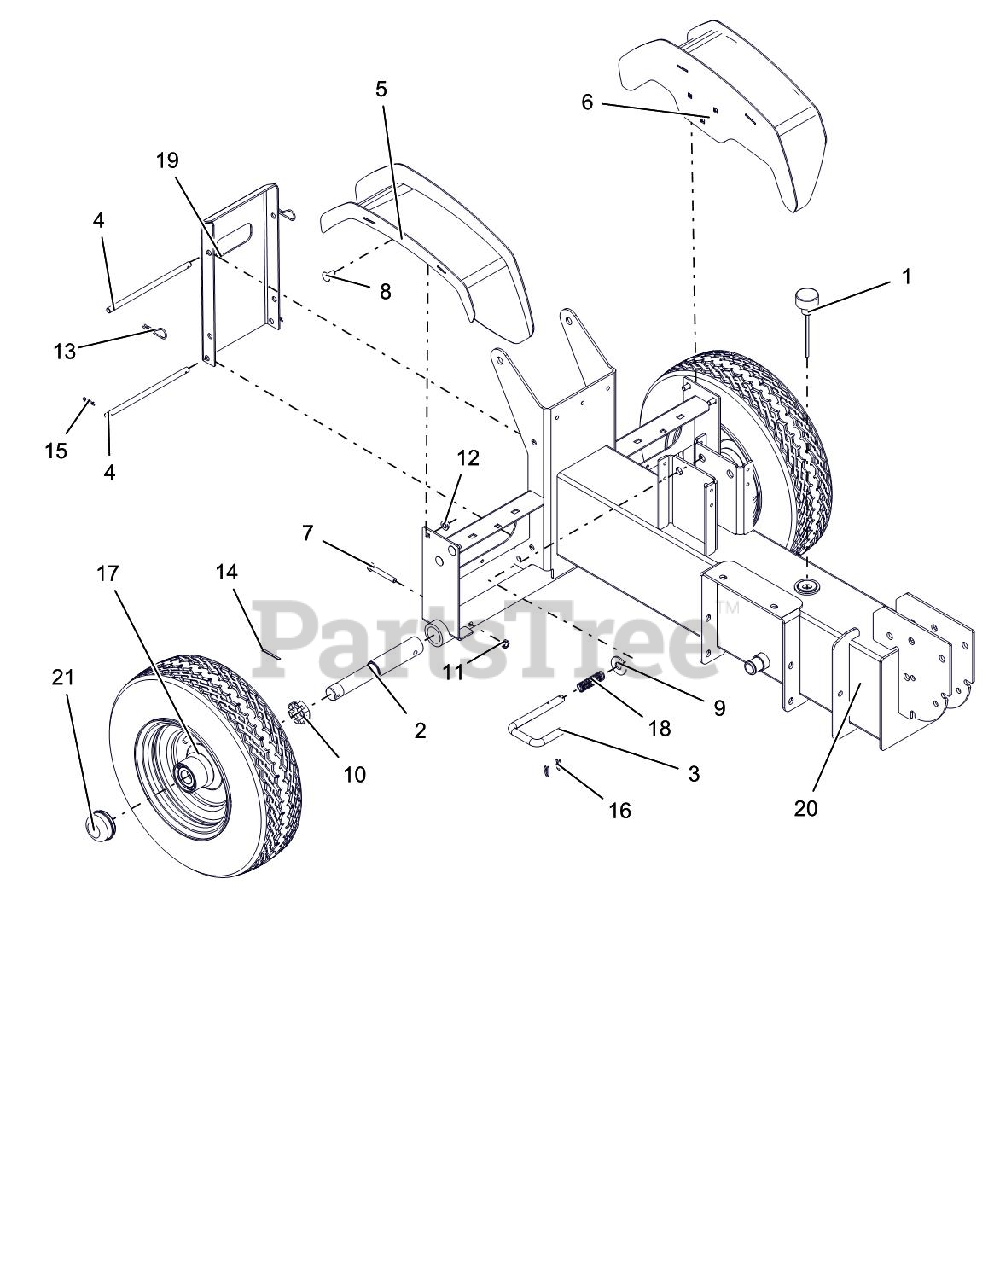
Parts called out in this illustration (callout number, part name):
1	BREATHER, DIPSTICK
2	AXLE, SPLITTER
3	LOCK, BEAM
4	PIN, .373 X 7.30 X 2X.109 THRU
5	WMT-FENDER-RH
6	WMT-FENDER-LH
7	@BLT-HEX .31-18X2.25 GR5 YWZC
8	@BLT-RDHDSQNK .31-18X.75 G5YZ
9	@WSHR-FL-STL.563X1.38X.109YWZC
10	NUT-SL 1.0-14
11	@NUT-LK-CTR .31-18 YWZC
12	@NUT-LK-TOP-FLG .31-18 YWZC
13	HAIRPIN, #7 CLIP .094X2.31 YWZ
14	@PIN-CTR .15X1.50 YWZC
15	PIN-HAIR, ENDRIES #25 YWZC
16	CLIP, SPRING
17	ASM,TIRE/WHEEL 4.8/4-8 P47GRAY
18	SPRG, COMP .058X.65X2.13 WLD15
19	REAR STAND W/DECALS (ARIENS)
20	CHASSIS W/SAFETY DECALS-27T-CE
21	CAP, DUST
